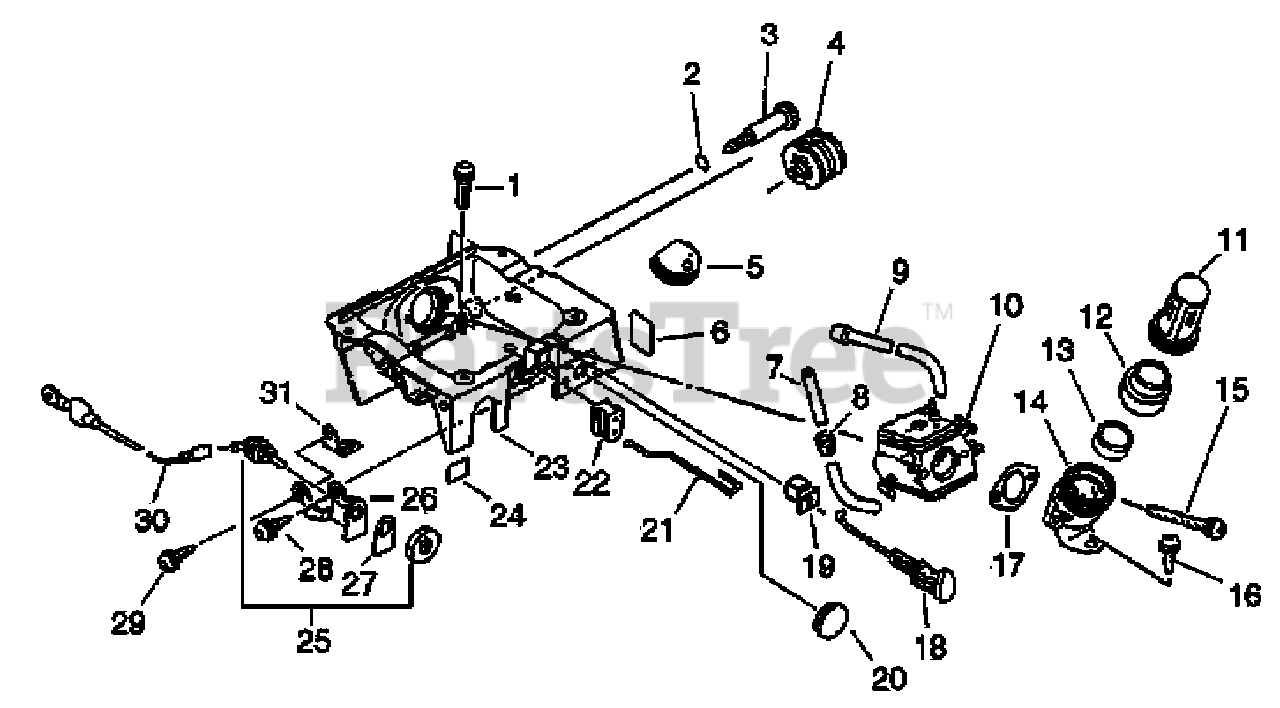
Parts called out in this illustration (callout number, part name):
1	BOLT 5×20
2	O-RING 7
3	SCREW, IDLE ADJUST - ORANGE
5	GROMMET, HOSE
6	LABEL, CAUTION - IDLE
7	PIPE, OIL
8	GROMMET
9	PIPE, IMPULSE
10	CARBURETOR - HDA-216
11	SCREEN, FILTER
12	CUSHION
14	MOUNT, AIR FILTER
15	SCREW 5×53
16	SCREW 5×14
17	GASKET, INTAKE
18	ROD, CHOKE
19	GROMMET, CHOKE
20	GROMMET, PLUG
21	ROD, THROTTLE
22	GROMMET, THROTTLE ROD
23	CASE, CARBURETOR
24	LABEL, STOP
25	SWITCH, ON-OFF
26	BRACKET, SWITCH
27	LABEL - SWITCH
28	SCREW 5×10
29	SCREW 4×10
30	LEAD - GROUND
31	PLATE, GROUND
